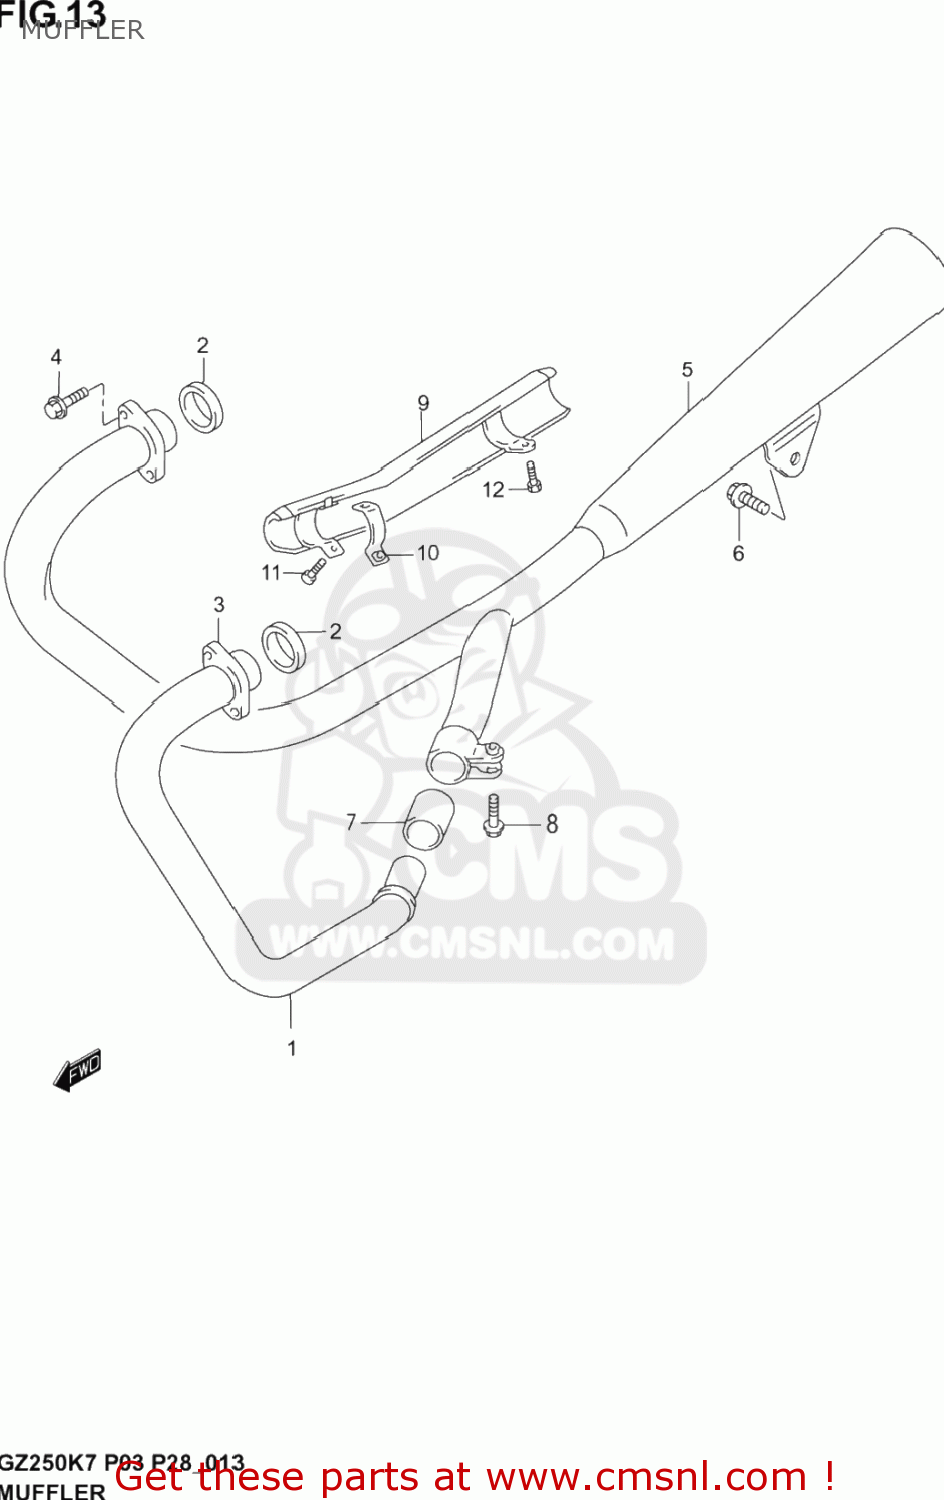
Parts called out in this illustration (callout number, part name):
1	PIPE,EXHAUST,L
2	GASKET,EXHAUST PIPE (NAS)
3	CLAMP,EXHAUST PIPE,L
4	BOLT(6X25)
5	MUFFLER
6	BOLT
7	CONNECTOR,MUFFLER
8	BOLT
9	COVER,MUFFLER
10	CLAMP,MUFFLER COVER
11	SCREW
12	SCREW
